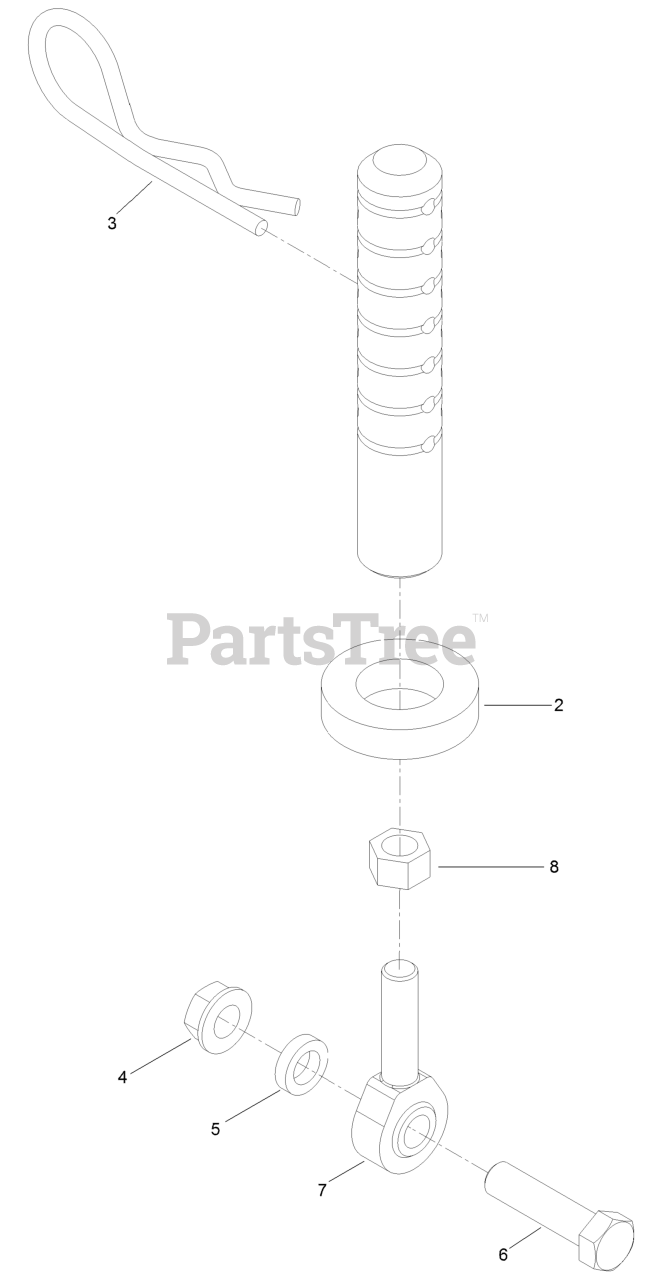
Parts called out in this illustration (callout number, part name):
2	SPACER-DECK SUPPORT
3	PIN-CUT HEIGHT
4	NUT-HHF, WHIZ
5	SPACER-IDLER
6	SCREW-HH
7	BALLJOINT
8	NUT-HJ
